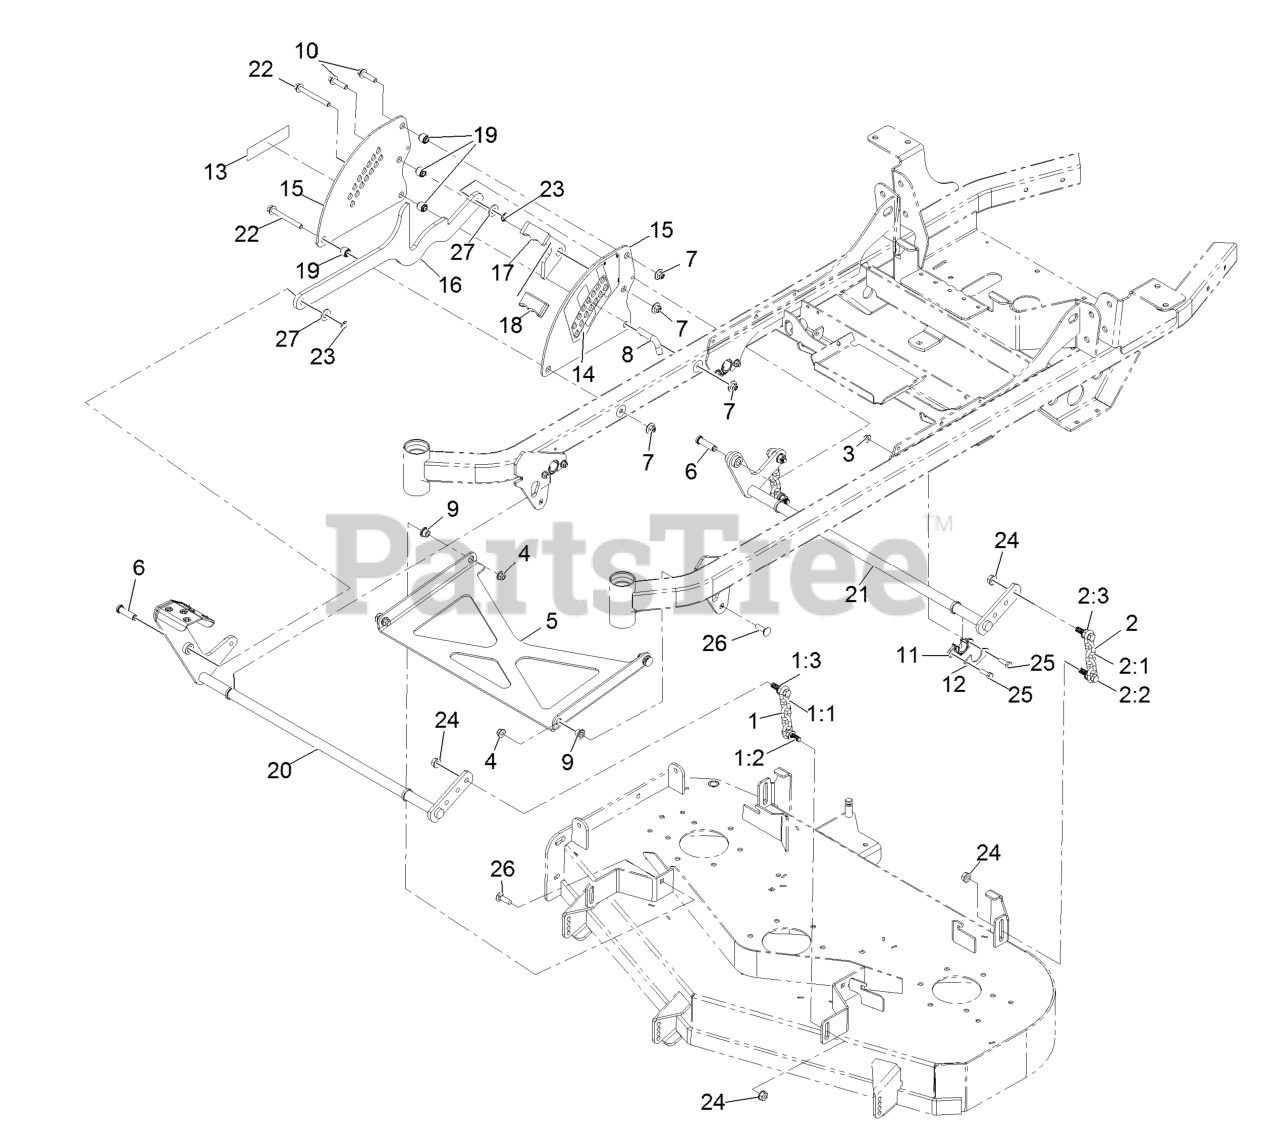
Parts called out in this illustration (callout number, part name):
1	DECK CHAIN ASM
1:1	CHAIN-LIFT, DECK
1:2	SCREW-HH
2	DECK CHAIN ASM
2:1	CHAIN-LIFT, DECK
2:2	SCREW-HH
3	NUT-HF, NI
4	NUT-HF, NI
5	STRUT-DECK
6	PIN-CLEVIS
7	Nut-Nyloc 3/8-16 Flg
8	PIN-HOC
9	BUSHING-FLANGED
10	SCREW-HHF
11	BUSHING-FLANGE
12	GUSSET-LIFT, DECK
13	DECAL-S-SERIES
14	DECAL-HEIGHT OF CUT
15	PLATE,DECK LIFT
17	TRANSPORT LOCK-HOC
18	GRIP-FLAT
19	SPACER-STEP, DOUBLE
20	WLD-DECK LIFT SHAFT FRT
21	WLD-DECK LIFT SHAFT RR
22	SCREW-HHF
23	RING-RETAINING, EXTERNAL
25	SCREW-HH
26	BOLT-CARR
27	WASHER-FLAT
